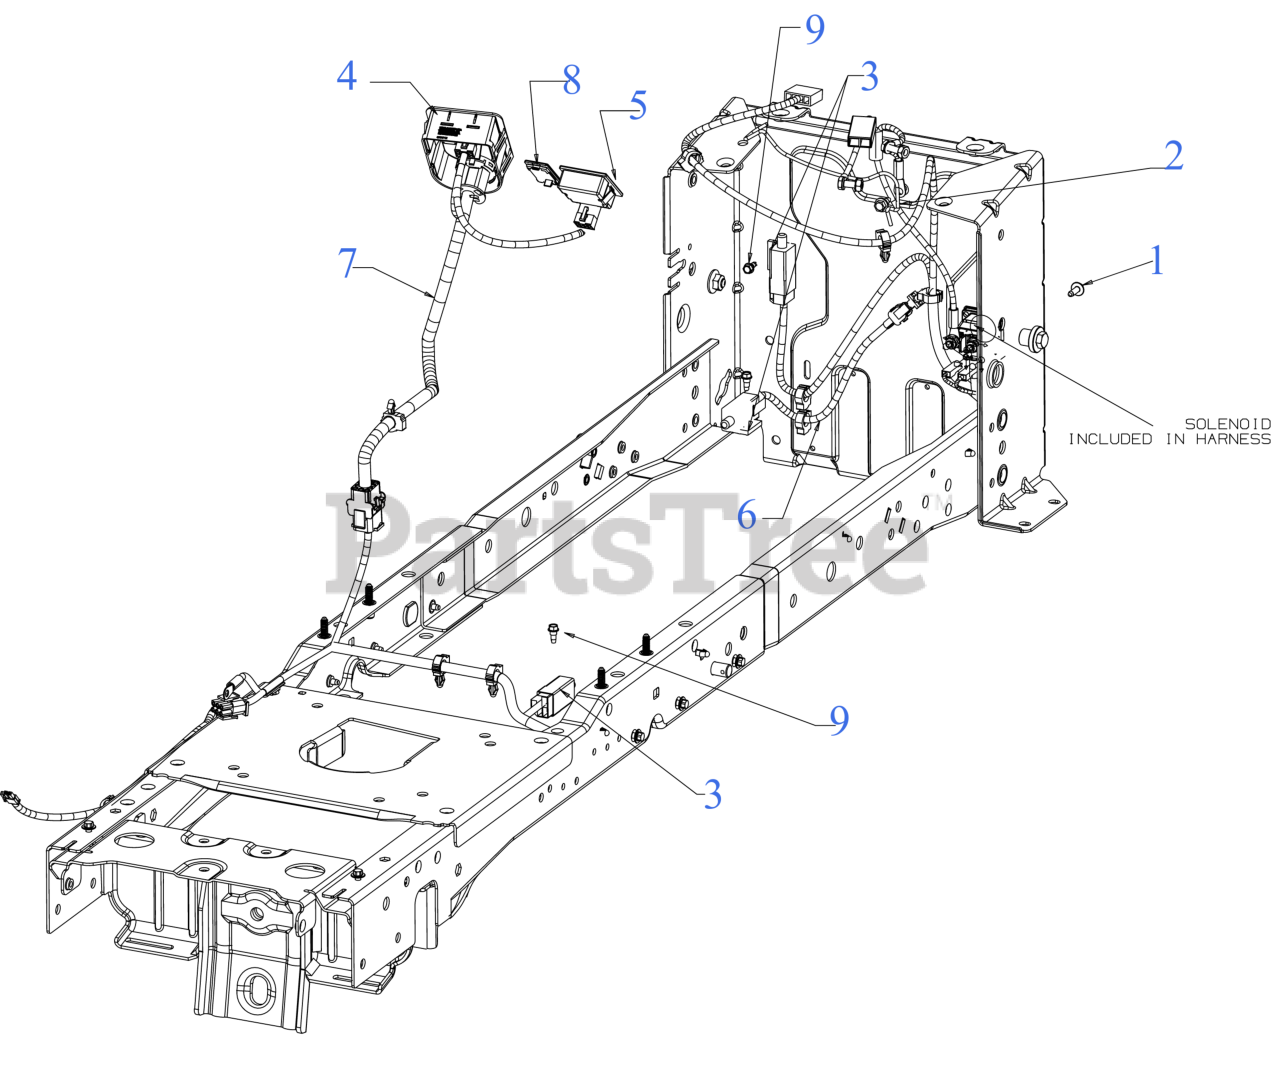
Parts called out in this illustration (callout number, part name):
1	SCREW M6-1 x .625
2	SCREW 1/4-20X.625
3	INTERLOCK SWITCH (NO/NC)
4	IGNITION MODULE SWITCH RMC (MAN PTO BLK)
5	HOUR METER/SERVICE MINDER
6	REVERSE HARNESS
7	HARNESS (MPTO/RMC/HRMTR/DC)
7	12V SOLENOID
9	SHOULDER SCREW
